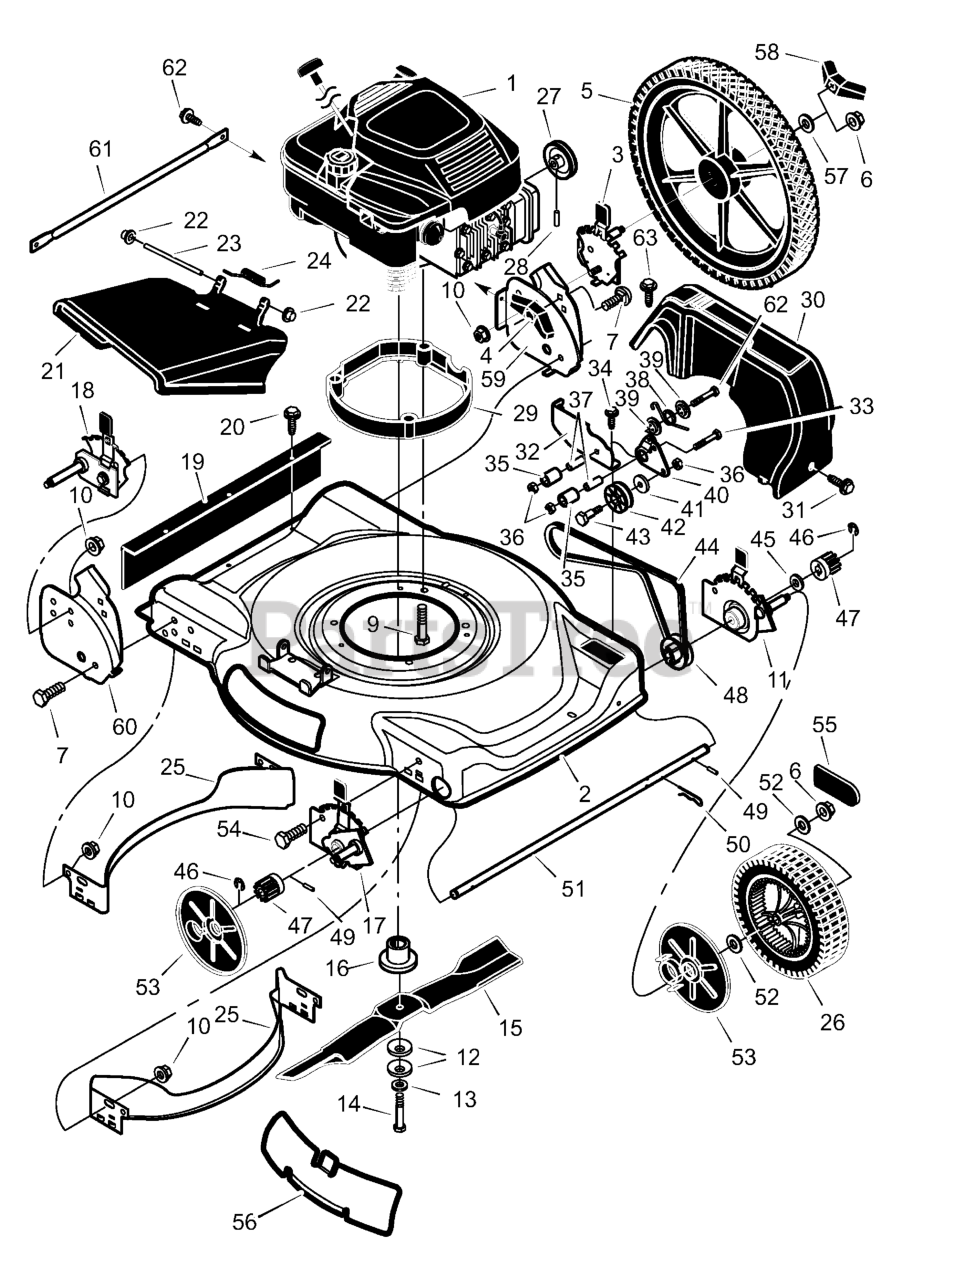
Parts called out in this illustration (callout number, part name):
1	Engine *
2	Housing
3	Height Adjuster, Left Rear
5	Wheel and Tire, Rear
6	Locknut, Flange
7	Bolt, Carriage
9	Bolt, Engine
10	Nut
11	Height Adjuster, Left Front
12	Washer, Belleville
14	Bolt, Hex
15	Blade, Mulcher
16	Adapter, Blade
17	Height, Adjuster, Right Frt.
18	Height, Adjuster, Right Rr.
19	Guard, Rear
21	Deflector, Chute
22	Push-On Cap
23	Pin, Pivot
26	Wheel and Tire, Drive
28	Pin, Spring
29	Base, Engine
30	Cover, Belt (Black)
32	Bracket, Idler Support
35	Idler, Backside
36	Locknut
37	Bearing
40	Arm, Pivot
42	Pulley, Idler
43	Bolt, Shoulder
44	Belt, Briggs & Stratton
46	Ring, Retainer
47	Gear, Pinion
49	Pin, Drive
50	Pin, Hair
52	Washer
53	Cover, Dust
54	Bolt
55	Hub Cap
56	Plate, Mulch
58	Knob, Axle
59	Bracket, Left Handle
60	Bracket, Right Handle
